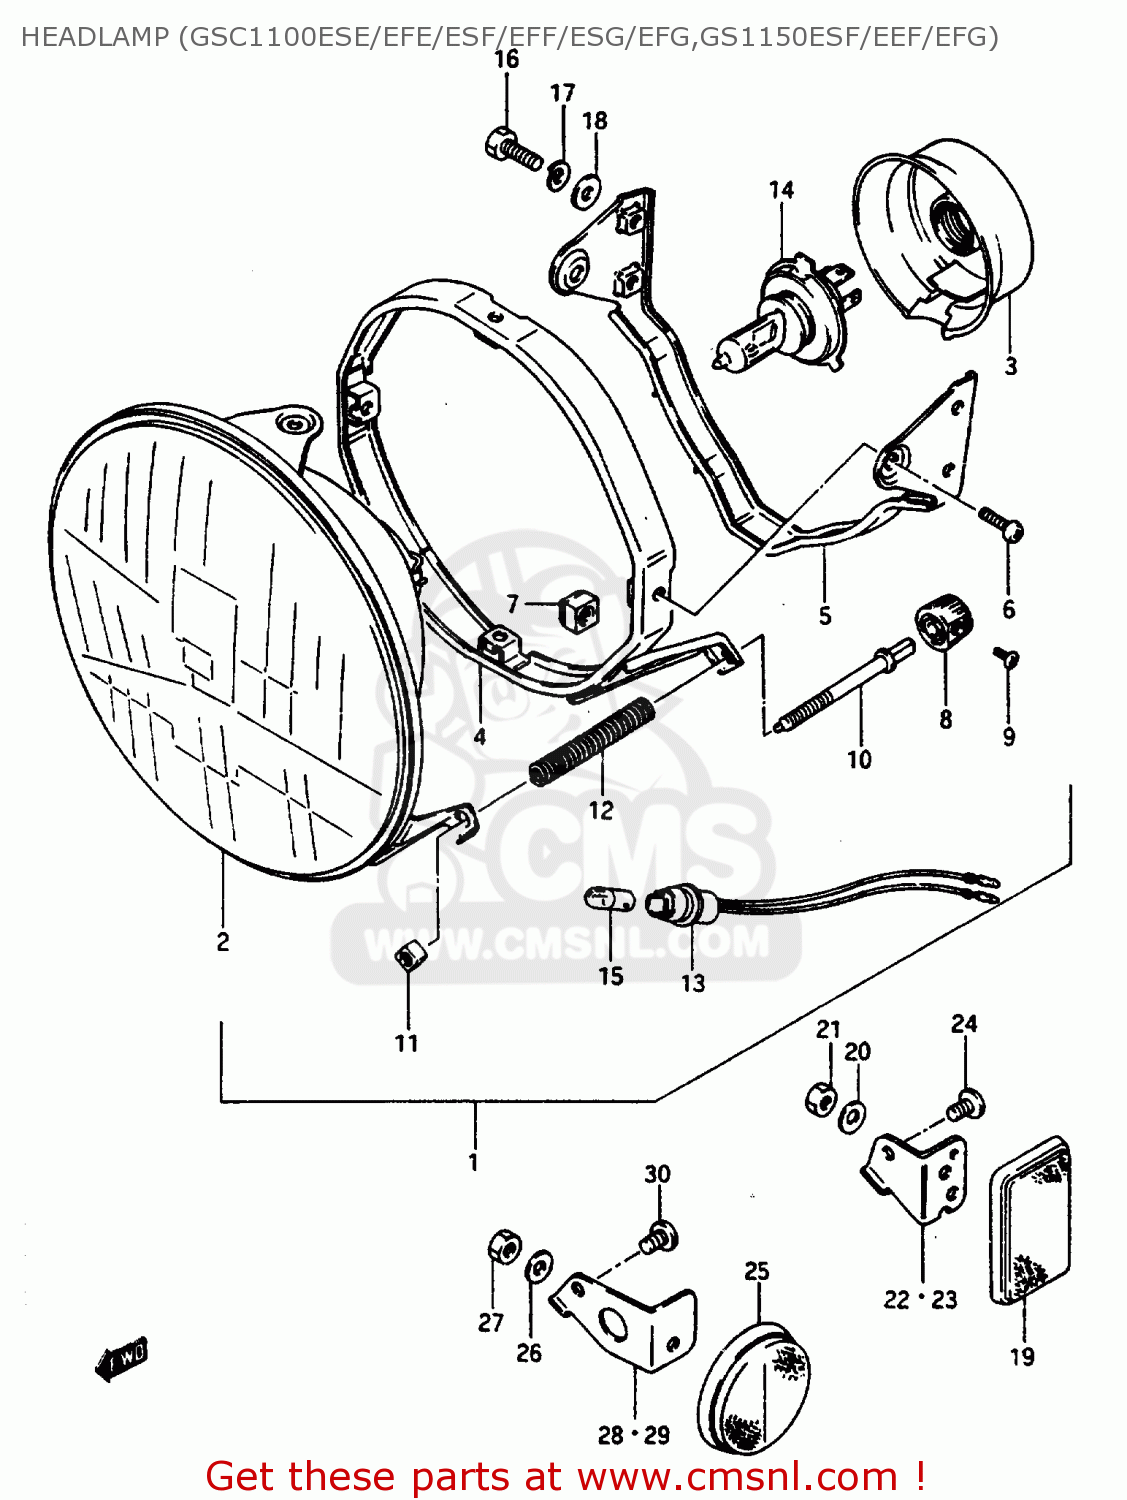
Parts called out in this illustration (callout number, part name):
1	HEADLAMP ASSY
2	UNIT
3	COVER,HEADLAMP SOCKET
4	RING,MOUNTING
5	HOUSING,LAMP UNIT
6	SCREW
7	NUT
8	KNOB,ADJUSTER
9	SCREW
10	SCREW,HEADLAMP ADJUST
11	NUT,HEADLAMP ADJUSTER
12	SPRING
13	SOCKET,PARKING
14	BULB(12V60/55W,H4)
15	BULB(12V4W)
16	BOLT 6X16
17	WASHER,LOCK
18	WASHER
19	REFLEX REFLECTOR, FRONT SIDE
20	WASHER,5MM
21	NUT ,5MM
22	BRACKET,FRONT SIDE REFLECTOR
23	BRACKET,FRONT SIDE REFLECTOR
24	SCREW
25	REFLECTOR,REFLEX FR
26	WASHER,5MM
27	NUT ,5MM
28	BRACKET, RH
29	BRACKET, LH
30	SCREW
